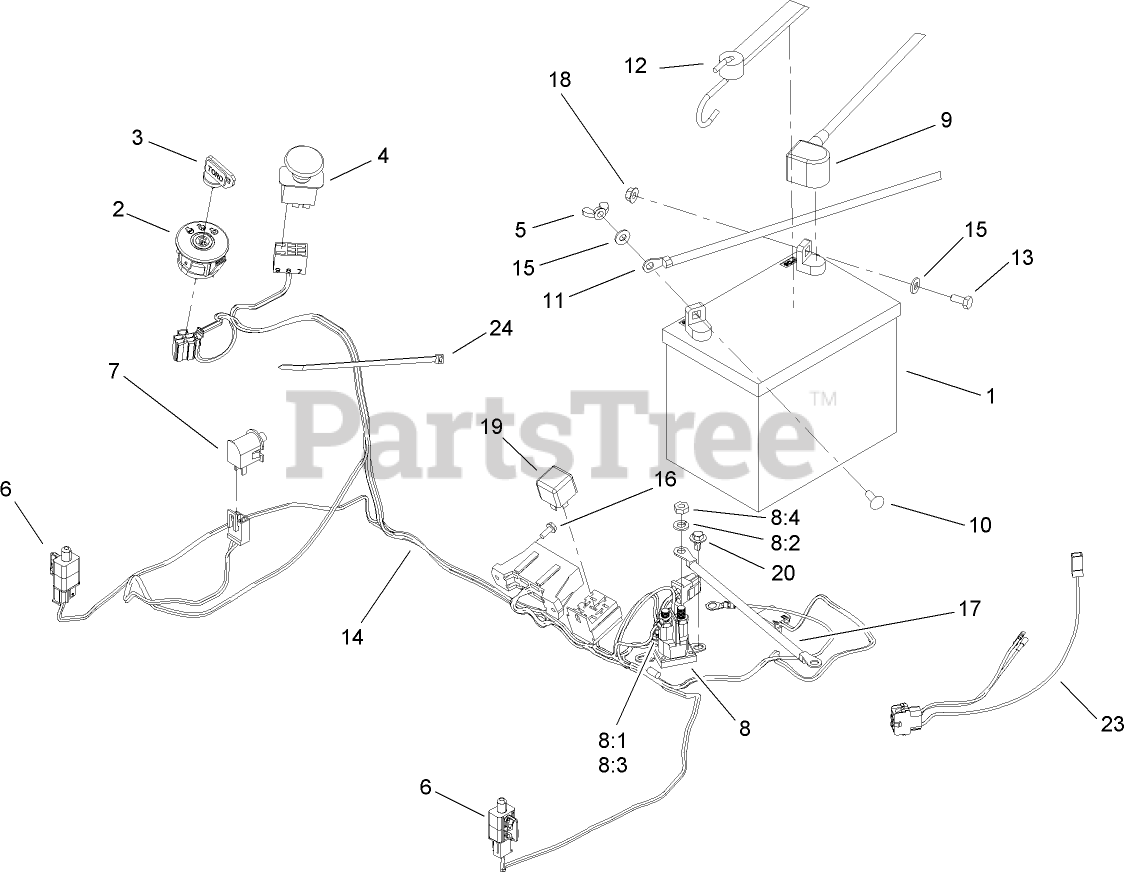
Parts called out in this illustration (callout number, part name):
1	BATTERY
2	SWITCH-IGNITION
3	KEY-IGNITION
4	SWITCH-PTO
5	NUT-WING
6	SWITCH
7	SWITCH-BAIL
8	SWITCH-SOLENOID
8:1	WASHER-LOCK
8:2	WASHER-LOCK
8:3	NUT-HEX
8:4	NUT-JAM
9	CABLE-BATTERY, RED
10	BOLT-CARR
11	CABLE-BATTERY, BLACK
12	HOLDDOWN-BATTERY
13	SCREW-HH
14	HARNESS-WIRE
15	WASHER-FLAT
16	SCREW-TAPTITE
17	CABLE-BATTERY, RED
18	NUT-HF
19	RELAY
20	SCREW-HHFTF
23	HARNESS-ADAPTER
24	TIE-CABLE
